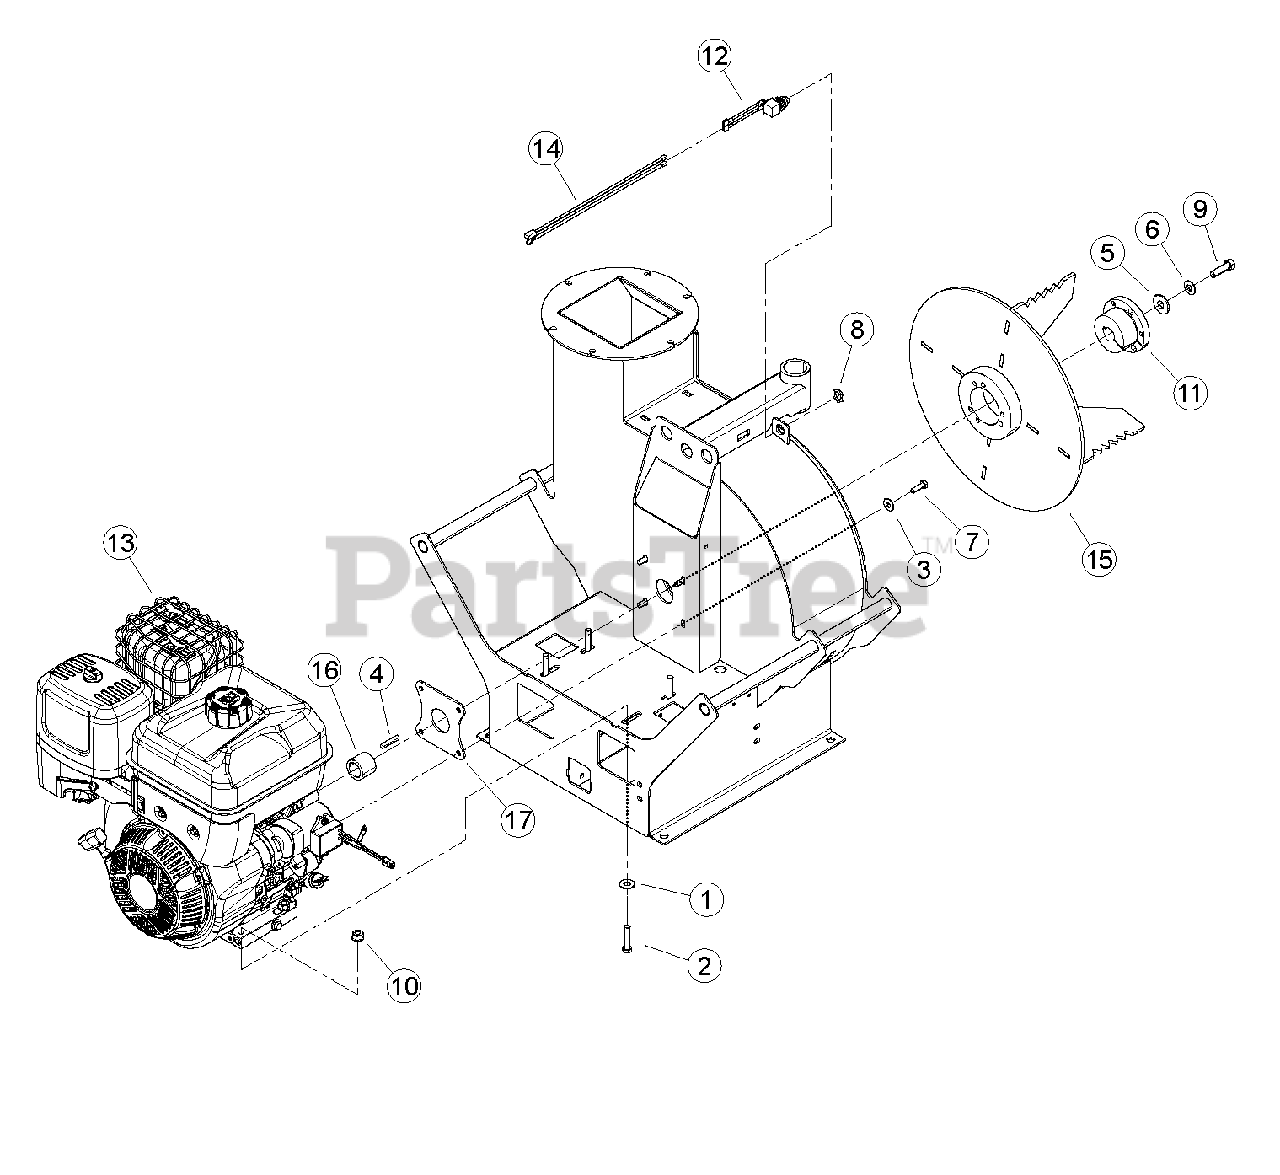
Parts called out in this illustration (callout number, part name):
1	WASHER, 3/8 FLAT
2	BOLT, 3/8 X 1-3/4 GR5 HCS ZP
3	WASHER, 5/16 FLAT
4	KEY, 1/4 SQ X 1-1/2 LG PLAIN
5	WASHER, 1/2 USS G8 ZP
6	WASHER, 3/8 GR8 USS ZP
7	BOLT, 5/16-24 X 1" HHCS GR5 ZP
8	NUT, 5/8-32 JAM
9	BOLT, 7/16 X 1-1/2 NF GR5 HEX ZP
10	NUT, 3/8-16 NYLOCK FLANGE
11	BUSHING, 1" SK
12	ASSEMBLY, SEALED SWITCH NORMALLY CLOSED
13	ENGINE, 420CC 2100 SERIES B&S (FOR SERVICE SEE ENGINE OWNER'S MANUAL OR NEAREST BRIGGS & STRATTON INDUSTRIAL ENGINE DEALER)
14	HARNESS, B&S ENGINE KILL SWITCH
15	WELDMENT, FAN "BEAR CLAW"
16	SPACER, 1.50 X 1.25 X 7/32 WALL
17	PLATE, ENGINE SPACER
